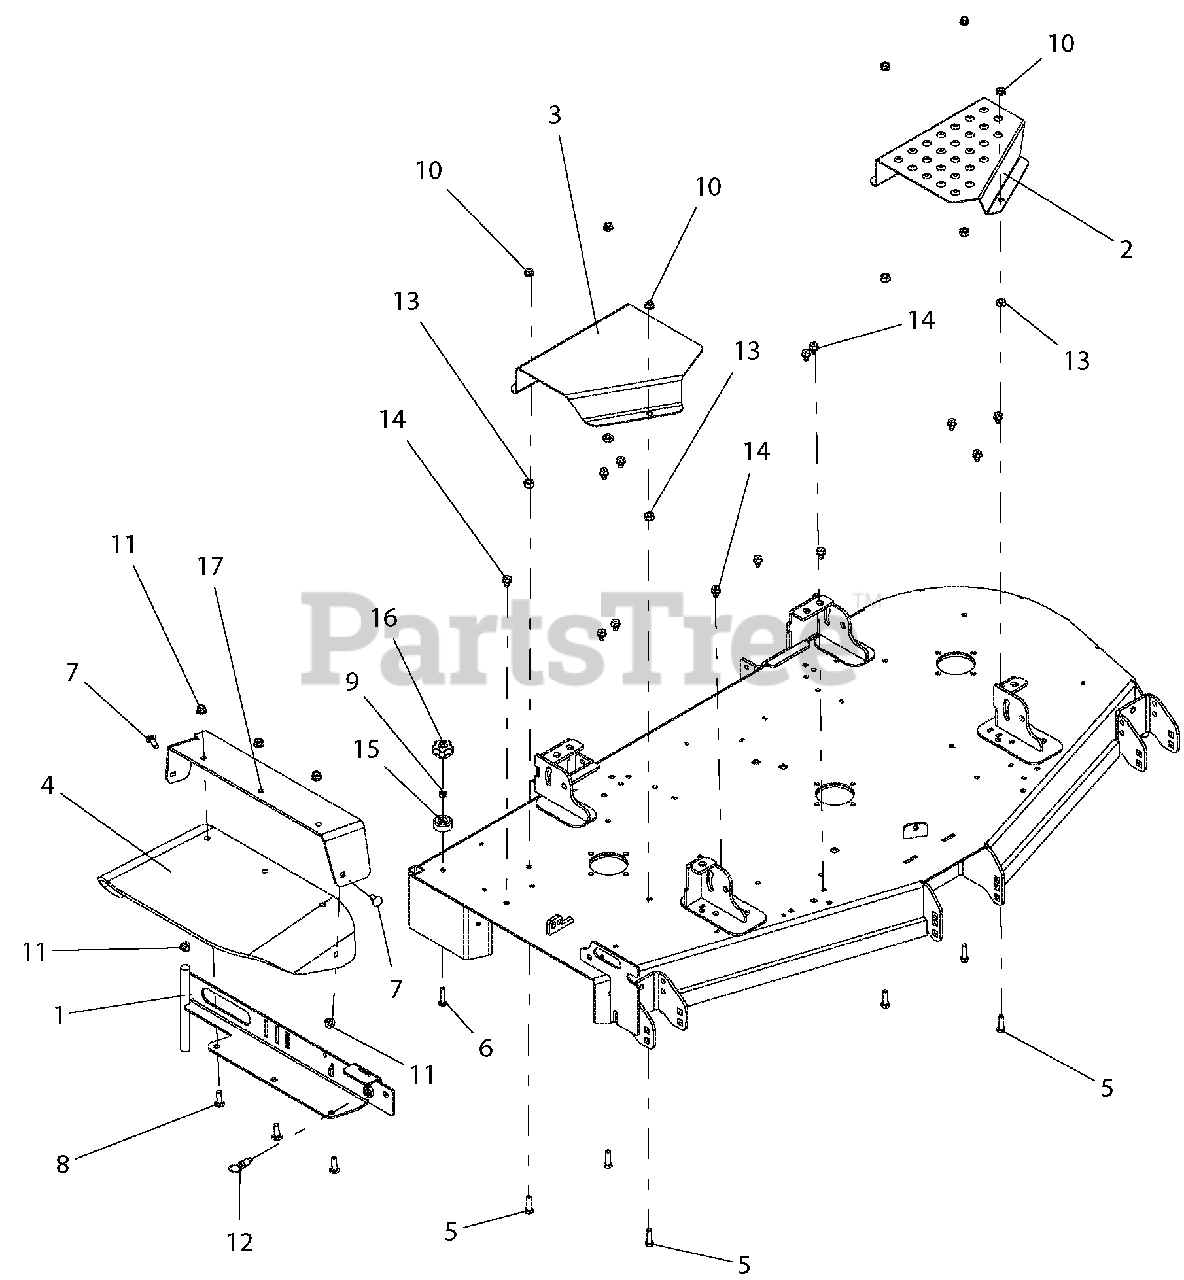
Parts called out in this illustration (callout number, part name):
1	WLDMT, 52"-60" DISCH CHUTE MTG-RED
2	GUARD, 60" LH DECK BELT-BLACK
3	GUARD, 60"-66" RH DECK BELT-BLACK
4	CHUTE, RUBBER DISCHARGE
5	BLT-HEX .38-16X1.25 GR5 YWZC
6	BLT-RDHDSQNK .31-18X1.50 G5 YWZC
7	BLT-RDHDSQNK .38-16X1.00 G5 YWZC
8	BLT-RDHDSQNK .38-16X1.25 G5 YWZC
9	NUT-LK-CTR .31-18 YWZC
10	@NUT-SPNLK-FLG .375-16 YWZC
11	NUT-LK-NYL-FLG .38-16 YWZC
12	PULL PIN,.50-13THDX.310 PLNGR
13	NUT-HEAVY HEX .38-16 YWZC
14	SCR-TAP .38-16X.50 HWH TR YWZ
15	BUMPER, RECESSED 1.50 X .63 W/.31 HOLE
16	KNOB, CLAMPING
17	DISCHARGE CHUTE SUPPORT W/SAFETY DECAL-RED
